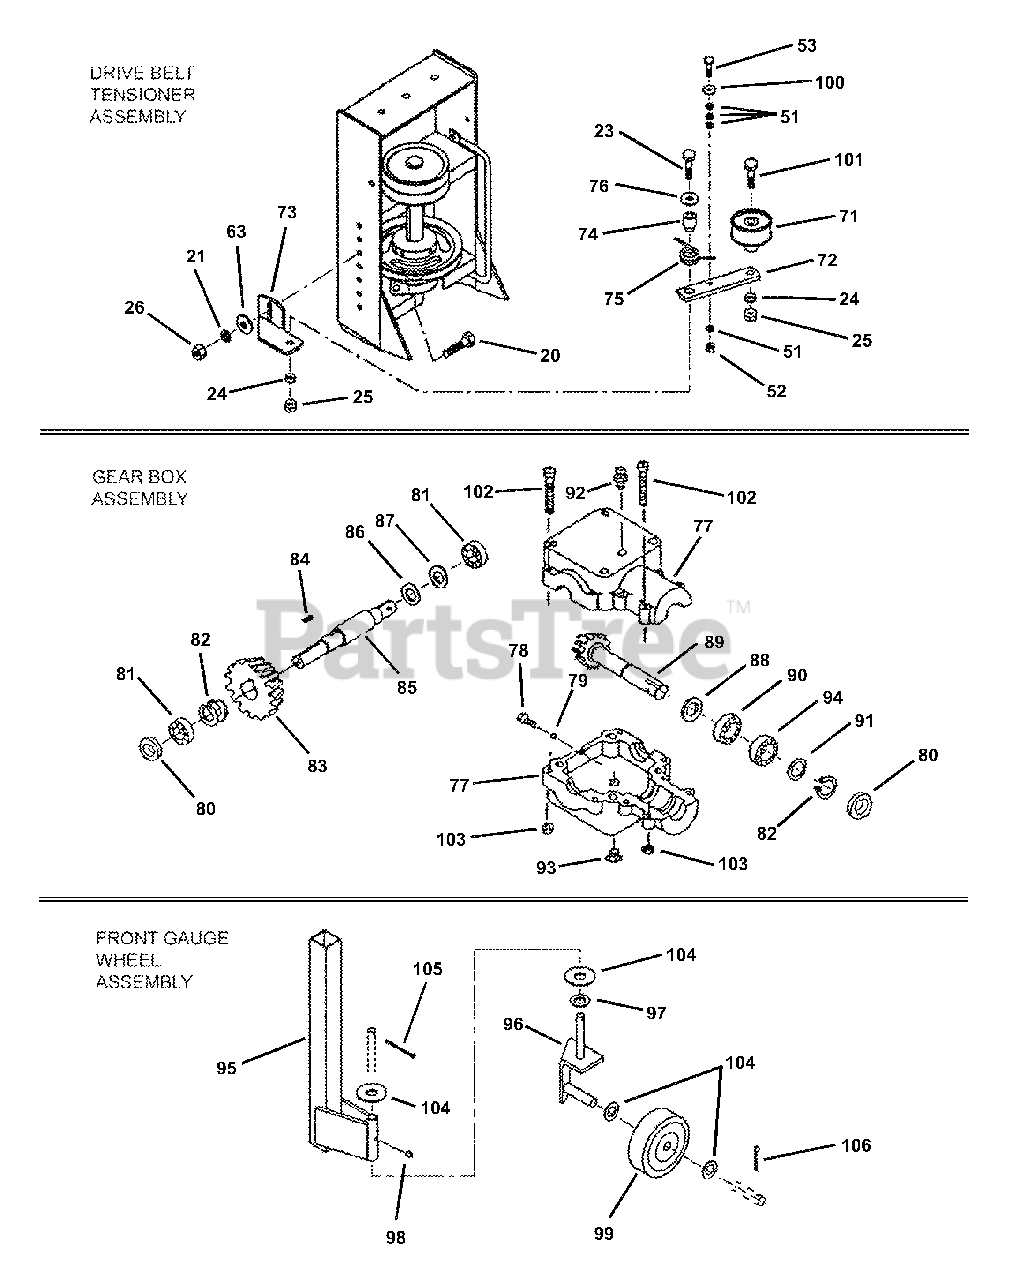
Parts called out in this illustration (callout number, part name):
20	BOLT, 5/16-18 x 1" Hex
21	WASHER, 5/16" Lock
23	BOLT, 3/8-16 x 2" Hex
24	WASHER, 3/8" Lock
25	NUT, 3/8-16 Hex
26	NUT, 5/16-18 Hex
51	DRIVE BELT, SP Models with Kohler Engine (B-57)
52	ROLL PIN, 1/4" Dia. x 1-1/4" long
53	BOLT, 5/16-18 x 3/4" Square Neck Carriage, Grade 5
63	WASHER, 3/8" Flat
71	PULLEY, Idler
73	SUPPORT, Lever
74	BUSHING
75	SPRING, Torsion
76	WASHER, 13/32" Dia. Hole
77	CASING (2 halves)
78	PLUG, 3/8"
80	OIL SEAL
81	BEARING
82	SNAP RING
83	GEAR, Z25 M3,5
84	PARALLEL KEY, A8 x 7 x 25
86	SHIM 25.6 x 0.8
87	SHIM 25.6 x 1.0
88	SHIM 25.6 x 0.7
89	PINION 29 M3.5
90	BEARING
91	SHIM 25.6 x 0.6
92	BREATHER
93	PLUG, Oil Level
94	BEARING
95	SUPPORT
96	BRACKET, Right Hand Wheel
97	NYLON WASHER, 0.630" I.D.
98	GREASE FITTING, 1/4" NF
99	WHEEL, 6" Dia. x 2"
100	WASHER, 5/16" Flat
101	BOLT, 3/8-16 x 1-3/4" Hex
103	NUT, M8 Hex
104	WASHER, 11/16" Flat
105	PIN, 3/16 x 1-1/2" Cotter
106	PIN, 1/4 x 1-1/2" Cotter
